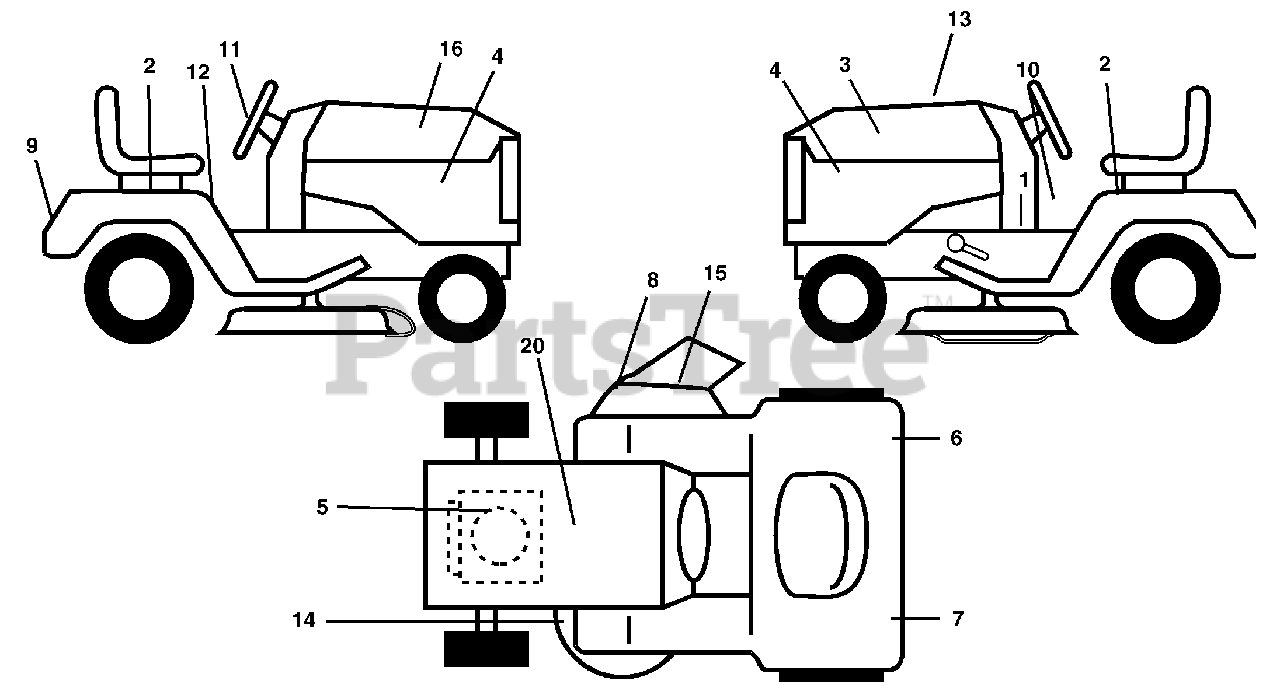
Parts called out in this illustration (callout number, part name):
1	Decal Dash
2	Decal Fender Auto
3	Decal Hood LH
4	Decal Side Panel
5	Decal HP Engine
6	Decal Reflector Rh
7	Decal Reflector Lh
8	Decal Warning Mower
9	Decal Fender Logo
10	Decal Fender Danger E/F
11	Decal Ins Strg Whl
12	Decal Fender Oper Cruise
13	Decal Final Replace Part
14	Decal V-Belt Schematic
15	Decal Deck B" 42"
16	Decal Hood Rh
20	Decal Bat Dan/Psn
